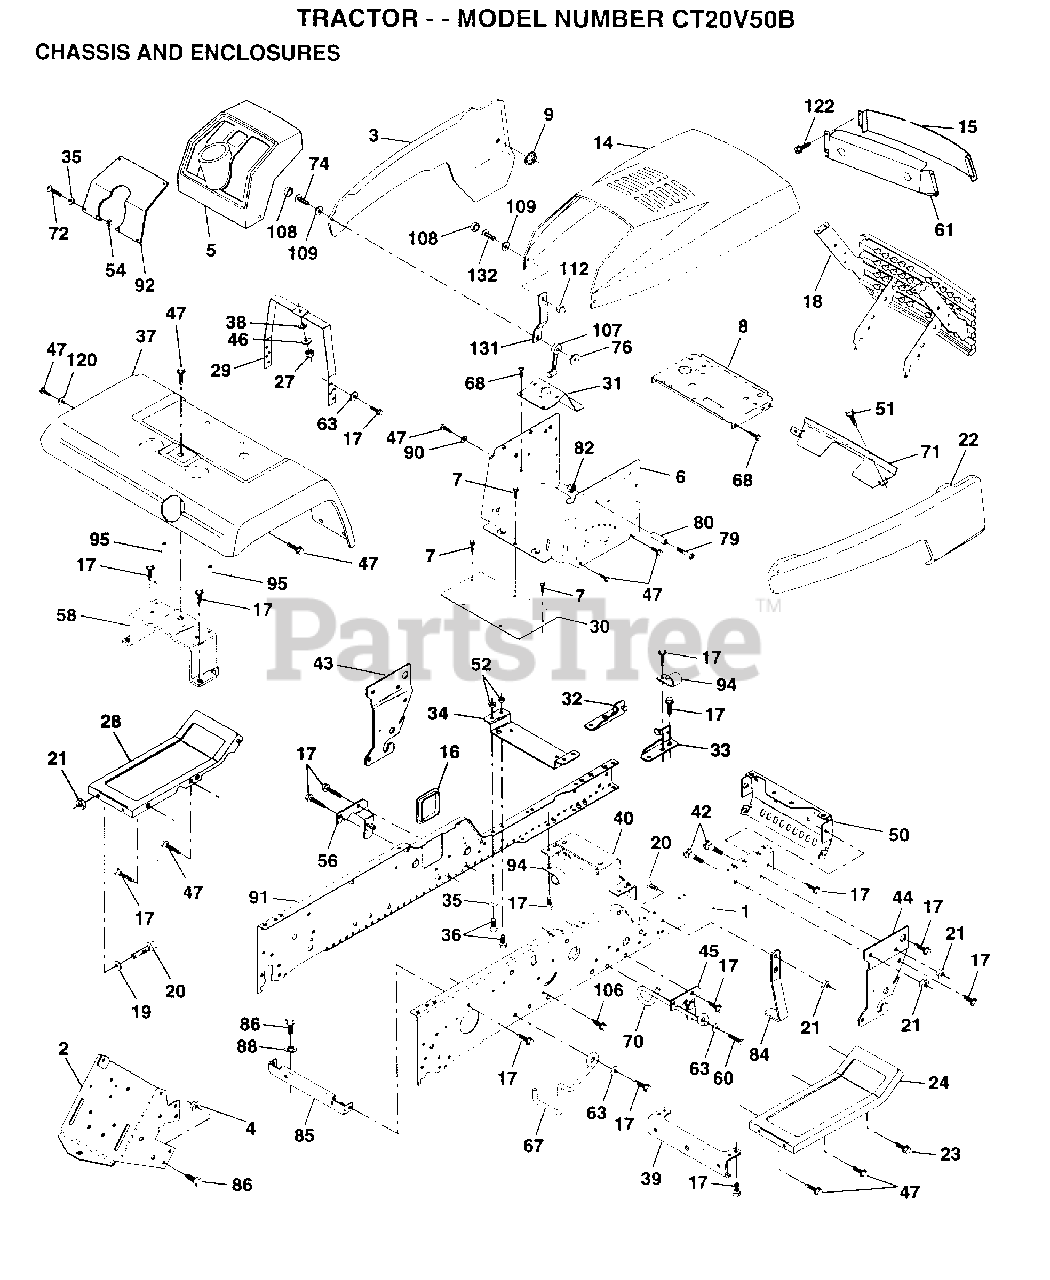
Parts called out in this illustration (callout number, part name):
1	"RAIL,FRAME RH"
2	DRAWBAR GT
3	PANEL PNT LH SIDE
4	NUT GTV
5	DASHBOARD BLACK
6	"DASH AS.,LOWER"
7	SCREW
8	SUPPORT.DASH.BTRY
9	PAL NUT LT
14	HOOD PNT YARDPRO
15	LENS.BAR.CLEAR
16	COVER ACCESS
17	SCREW
19	WASHER
22	PANEL PNT RH SIDE
23	SCREW GTV
24	FOOTREST.RH.LT/GT
28	FOOTREST.LH.LT/GT
29	DASH.SUPT.YP/HUSQ
30	SADDLE.SCR.6SP
31	BRAKET.SUPT.STEER
32	BRACKET ASM FRAME
33	BRACKET ASM FRAME
34	BRACKET.ENG.SUPT.
35	WASHER
36	BOLT
37	FENDER.PNT.MS-550
38	LOCKWASHER
39	BRACKET.AXLE.FRT.
43	BRACKET.SUS.FT.LH
44	BRACKET.SUS.FT.RH
46	WASHER PM
47	SCREW LT
50	BRACKET.CHASSIS.
51	SCREW CRT
58	BRKT.ASM.FENDER
60	SCREW
61	BEZEL.1 PC
63	WASHER
67	GUIDE BELT TRANS
68	SCREW LT
70	GUIDE.BELT.MID.SP
71	STRAP.PNT.GRILLE
72	SCREW
74	SCREW
75	LOCKWASHER
76	WELDNUT
79	SCREW
80	SPACER LT
84	STOP.OVER.CENTER
85	BRACKET.SUPT.TRAN
86	BOLT
88	LOCKWASHER
90	LOCKWASHER
91	"RAIL,FRAME LH"
92	PLATE SLKSCR YP
94	CLIP GTV
95	NUT-PUSH YT
107	HOOD LATCH T
108	SNAP CAP LT
109	WASHER LT
112	ACORN NUT RB
120	WASHER HYT
131	BKT.SPT.HOOD/PANL
132	SCREW.10-24X3/8.
